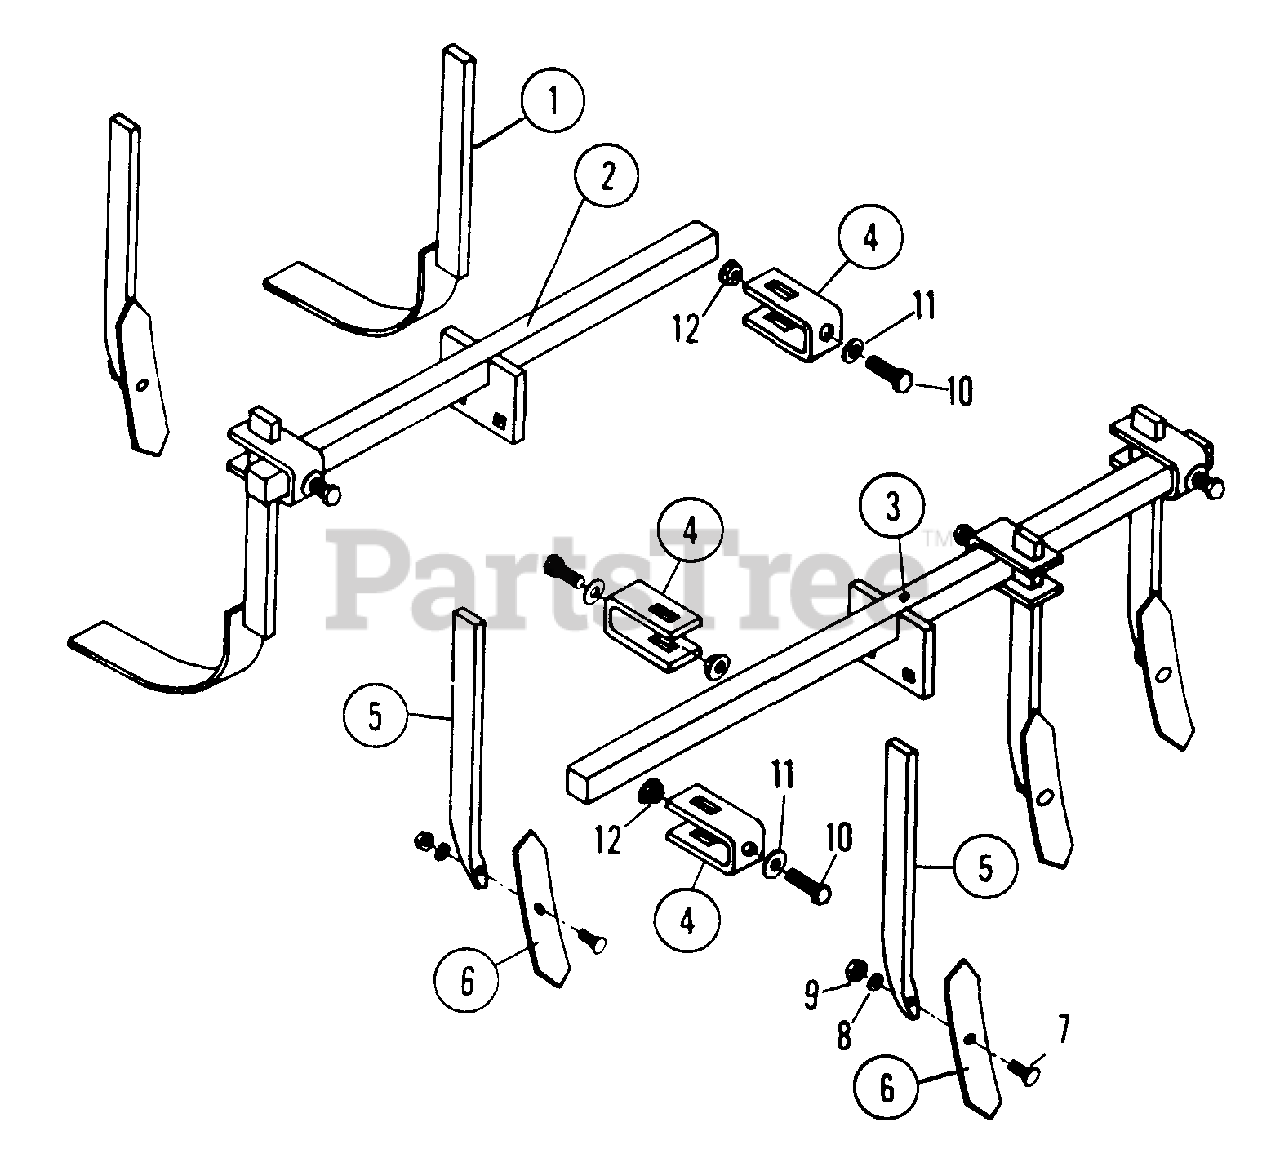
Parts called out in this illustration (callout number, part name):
1	GAUGE-SHOE
2	BAR, 26" CROSS
3	BAR, 36" CROSS
4	CLAMP, Shank
6	SHOVEL, PLOW
7	BOLT, 3/8 x 1-1/4 PLOW
8	LOCKWASHER, 3/8"
9	NUT, 3/8 HEX
10	BOLT, 1/2 x 1-1/2 HEX HEAD
11	WASHER, 1/2" PLAIN
12	NUT, 1/2 FLANGE
